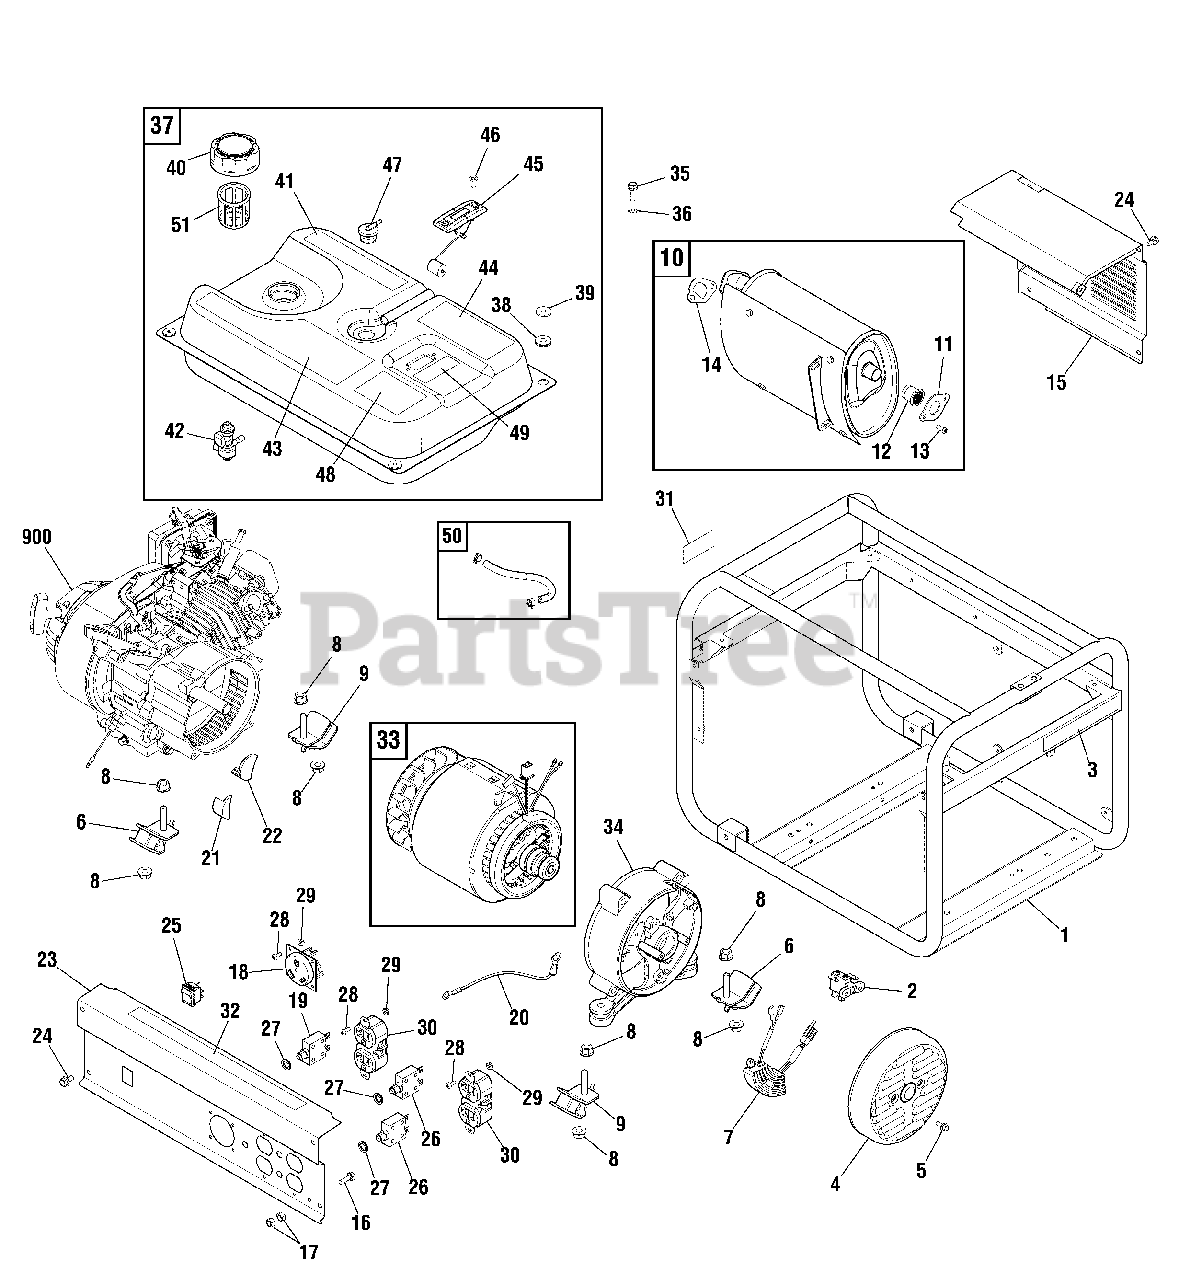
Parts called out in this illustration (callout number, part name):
5	* BOLT, M5 x 12
6	MOUNT-VIBRATION
7	VOLTAGE REGULATOR
8	* NUT, Flange, M8
9	MOUNT-VIBRATION
12	SPARK ARRESTOR
13	* SCREW, M5 x 12
14	GASKET-MUFFLER
15	COVER-MUFFLER
16	* BOLT, M5 x 16
17	* NUT, M5
19	CIRCUIT BREAKER
23	PANEL-CONTROL
24	* BOLT, M6 x 12
26	BREAKER-CIRCUIT
28	* SCREW, M4 x 14
29	* NUT, Flange, M4
34	CARRIER-BEARING
35	* BOLT, M6 x 20
36	* WASHER, Lock, M6
38	MOUNT-VIBRATION
46	* SCREW, M5 x 10
50	KIT-FUEL HOSE
900	** ENGINE
